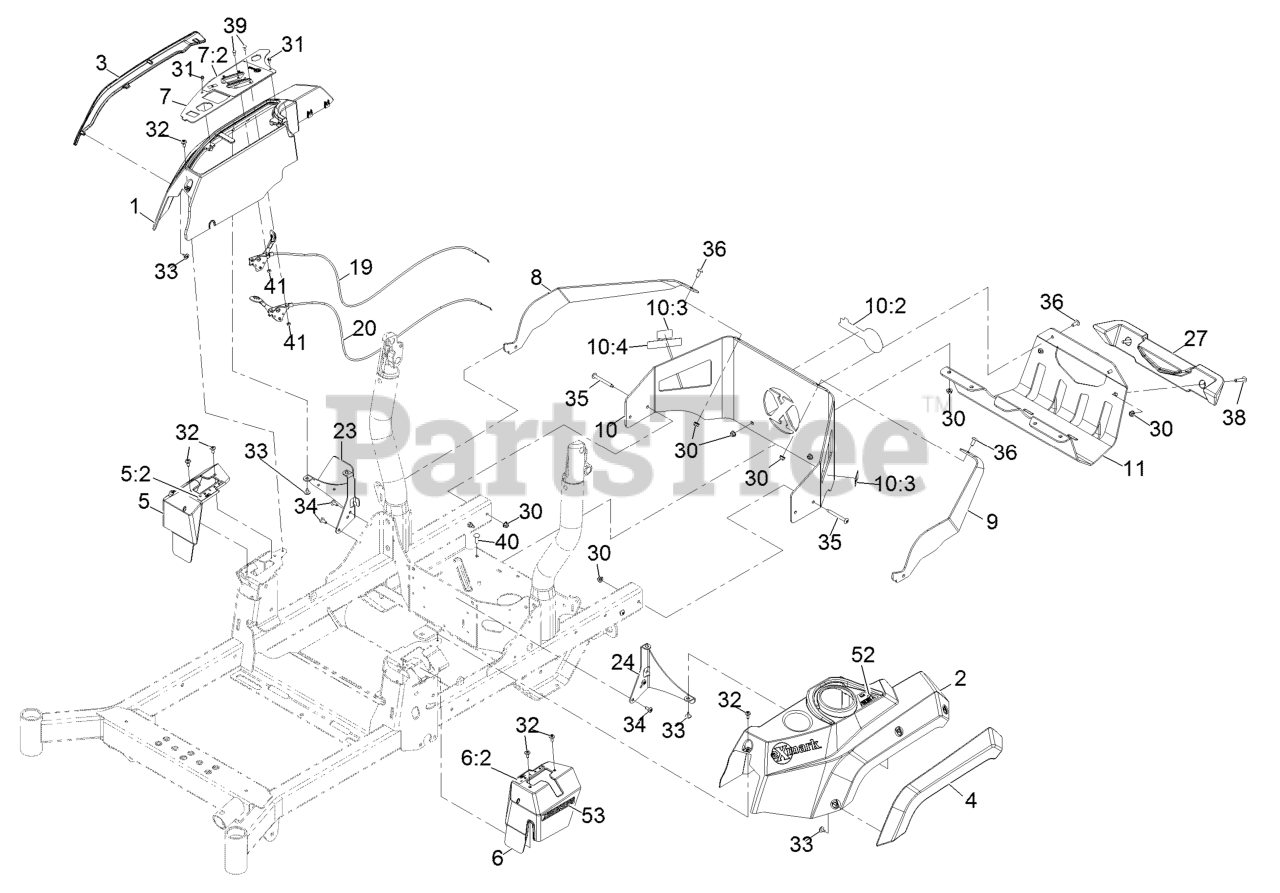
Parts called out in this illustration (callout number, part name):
1	Console-Exmark, RH
2	Console, LH
3	Fender-RH
4	Fender-LH
5	Cover-Control, Motion (RH)
5:2	Decal-Control, Motion (RH)
6	Cover-Control, Motion (LH)
6:2	Decal-Control, Motion (LH)
7	Ctrl Panel ASM W/Decal
7:2	Decal-Control Panel
8	Support-Upper, RH
9	Support-Upper, LH
10	Rear Guard ASM
10:2	Decal-Exmark Logo
10:3	Decal-Warning
10:4	Decal-Arrester, Spark
11	Guard-Muffler
19	Cable-Control, Choke
20	Cable-Control, Throttle
23	Support-Console, RH
24	Bracket-Console, LH
30	Nut-Nyloc 5/16-18 Flg
31	Screw-HWH #10-14 X 1/2
32	Screw-1/4-20 X 1/2 Tf Torx Plus
33	Screw-HWH #10-14 X 1/2 Torx
34	Screw-1/4-20 X .65 Torx Plus
35	Screw-Truss HD 5/16-18 X 2 3/4 Torx Plus
36	Screw-Truss HD 5/16-18 X 3/4 Torx Plus
38	Screw-Truss HD 5-16-18 X 1 1/2 Torx Plus
39	Bolt-Carriage #10-24 X 1/2
40	Bolt-Carriage 5/16-18 X 1 Sp
41	Nut-Nyloc #10-24
52	Decal-Fill, Fuel
53	Decal-X-Series
